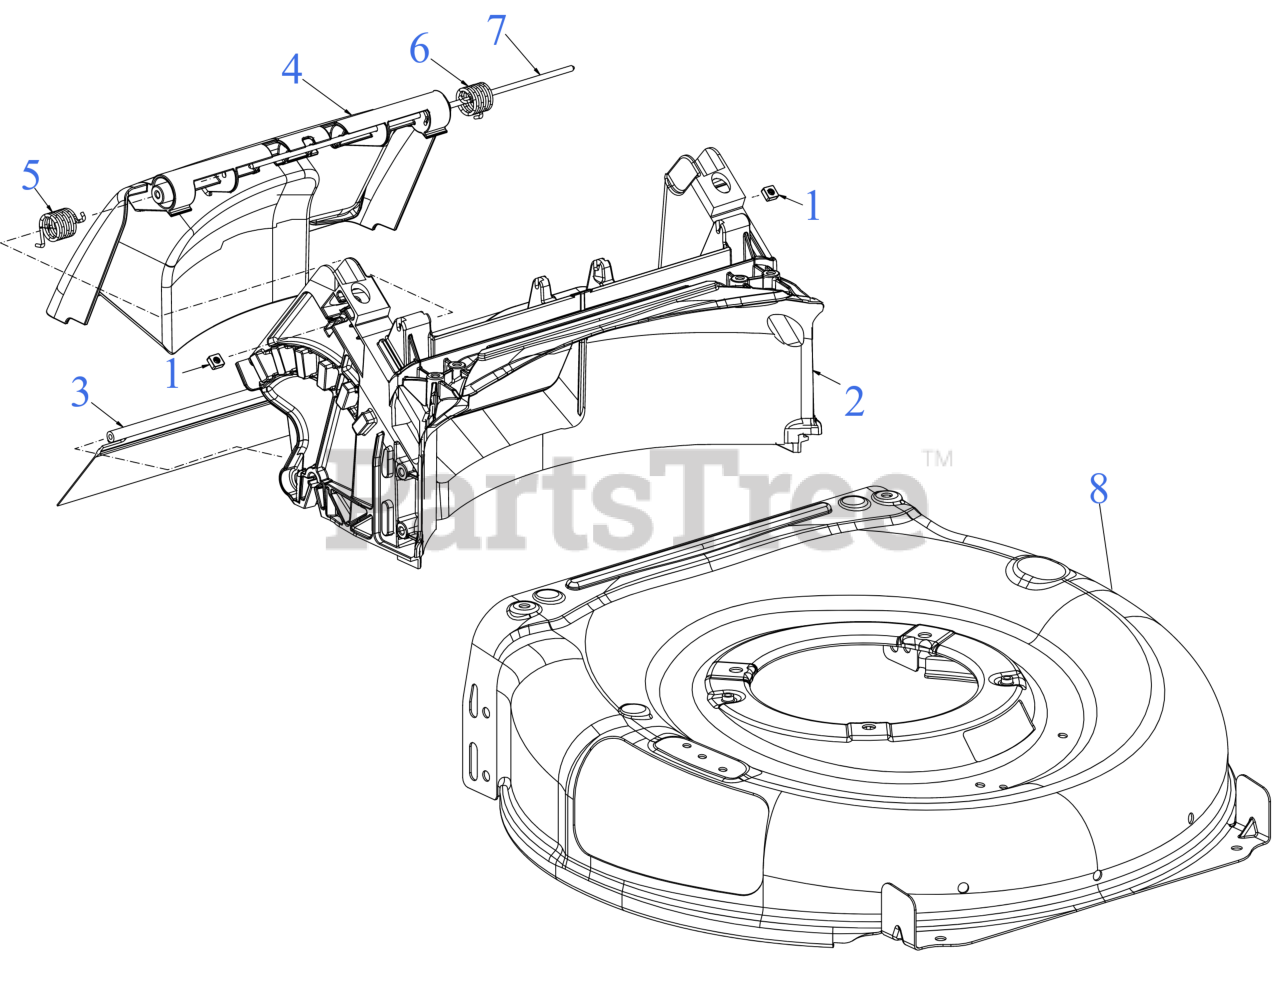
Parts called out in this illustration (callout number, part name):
1	SQUARE NUT 1/4-20
2	REAR DOOR & BAFFLE ASSEMBLY
3	TRAILSHIELD
4	REAR DOOR & BAFFLE ASSEMBLY
5	TORSION SPRING (RH)
6	TORSION SPRING (LH)
7	REAR DOOR PIVOT ROD
